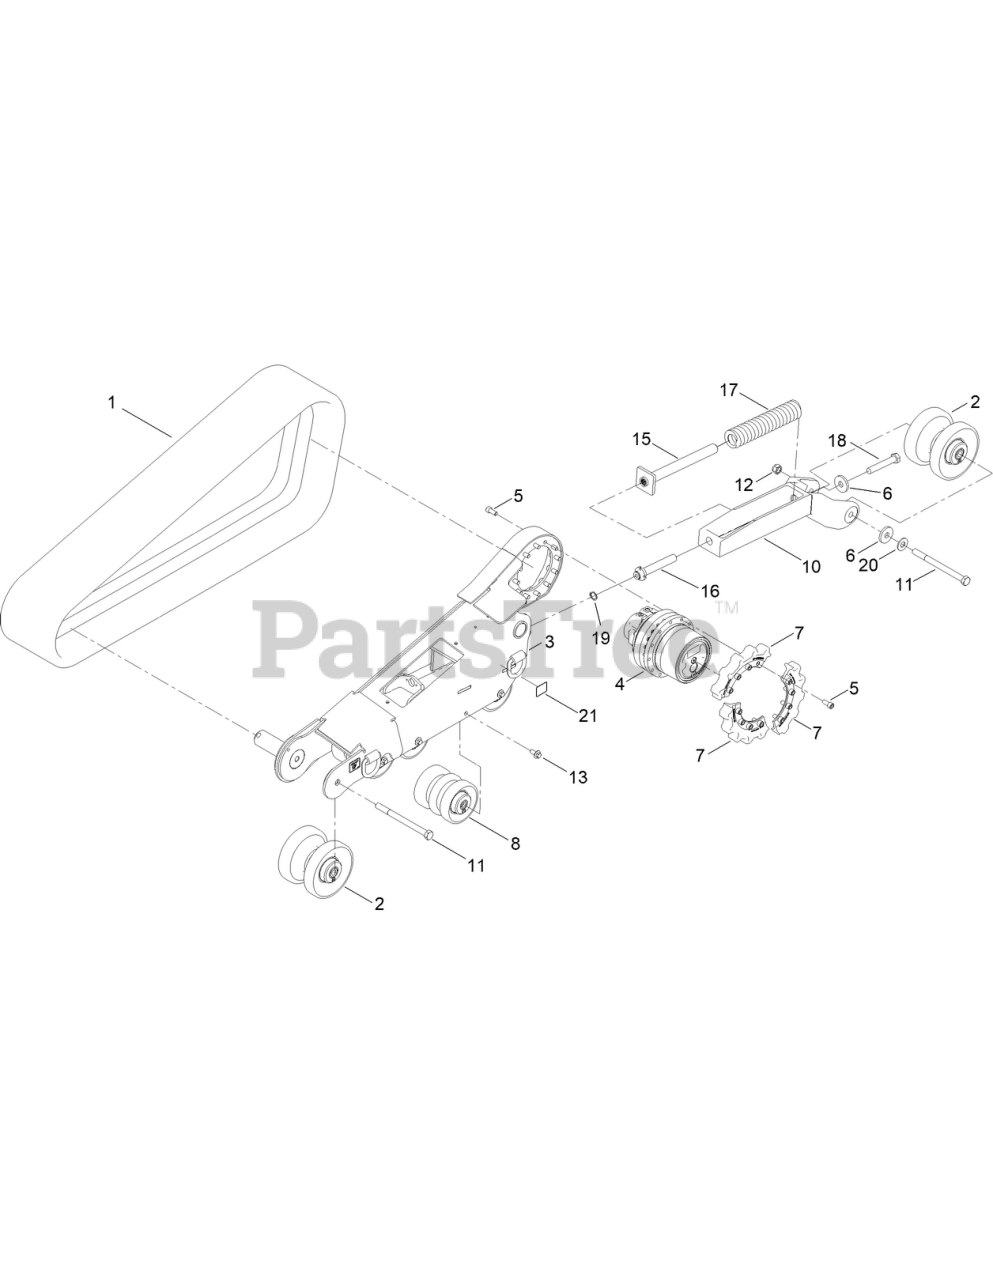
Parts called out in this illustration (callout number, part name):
1	TRACK-MERT,
2	FRONT WHEEL ASM
3	LH TRACK MOUNT ASM
4	DRIVE-TRACK
5	SCREW-HSH
6	WASHER-WHEEL
7	SPROCKET-DRIVE
8	ROAD WHEEL ASM
10	TENSIONER ASM
11	BOLT-HH
12	NUT-HEX
13	SCREW-HHF
15	SPRING CATCH ASM
16	SCREW-TENSIONER
17	SPRING-COMPRESSION
18	BOLT-TAP
19	RING-RETAINING, EXTERNAL
20	WASHER-PLAIN
21	DECAL-TIE DOWN
